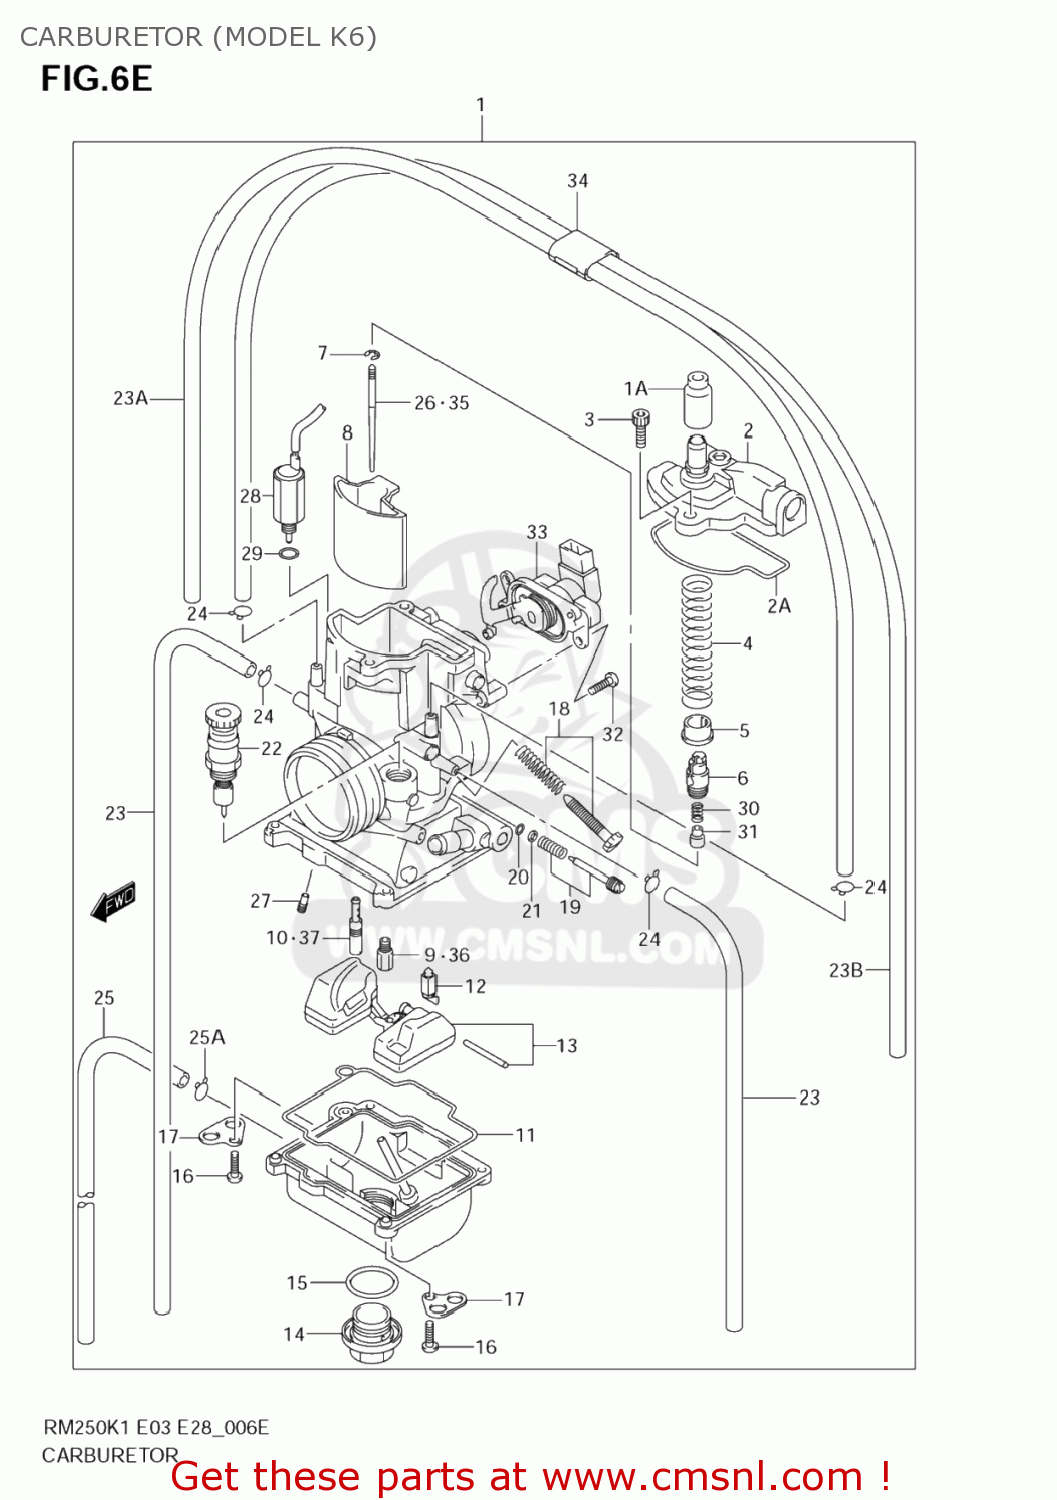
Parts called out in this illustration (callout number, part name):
1	CARBURETOR ASSY
1A	CAP,CARBURETOR
2	TOP
2A	O RING
3	SCREW
4	SPRING,THROTTLE VALVE
5	COLLAR,THROTTLE VALVE
6	HOLDER,CABLE
7	CLIP,NEEDLE
8	VALVE,PISTON
9	JET,MAIN(168)
10	JET,SLOW(48)
11	GASKET,FLOAT CAHMBER
12	VALVE SET,FLOAT
13	FLOAT SET
14	BOLT,DRAIN
15	O RING
16	SCREW
17	PLATE
18	SCREW SET,STOP
19	SCREW SET,AIR
20	O RING
21	WASHER
22	STARTER VALVE
23	HOSE(4X7X620)
23A	HOSE(4X7X620)
23B	HOSE(4X7X620)
24	CLIP
25	HOSE(3.5X6.5X600)
25A	CLIP
26	NEEDLE,JET(NECJ)
27	JET,POWER(45)
28	SOLENOID ASSY
29	O RING
30	SPRING
31	COLLAR
32	SCREW
33	SENSOR ASSY
34	CLIP
35	NEEDLE,JET(NECF)
36	JET,MAIN(150)
37	JET,SLOW(35)
